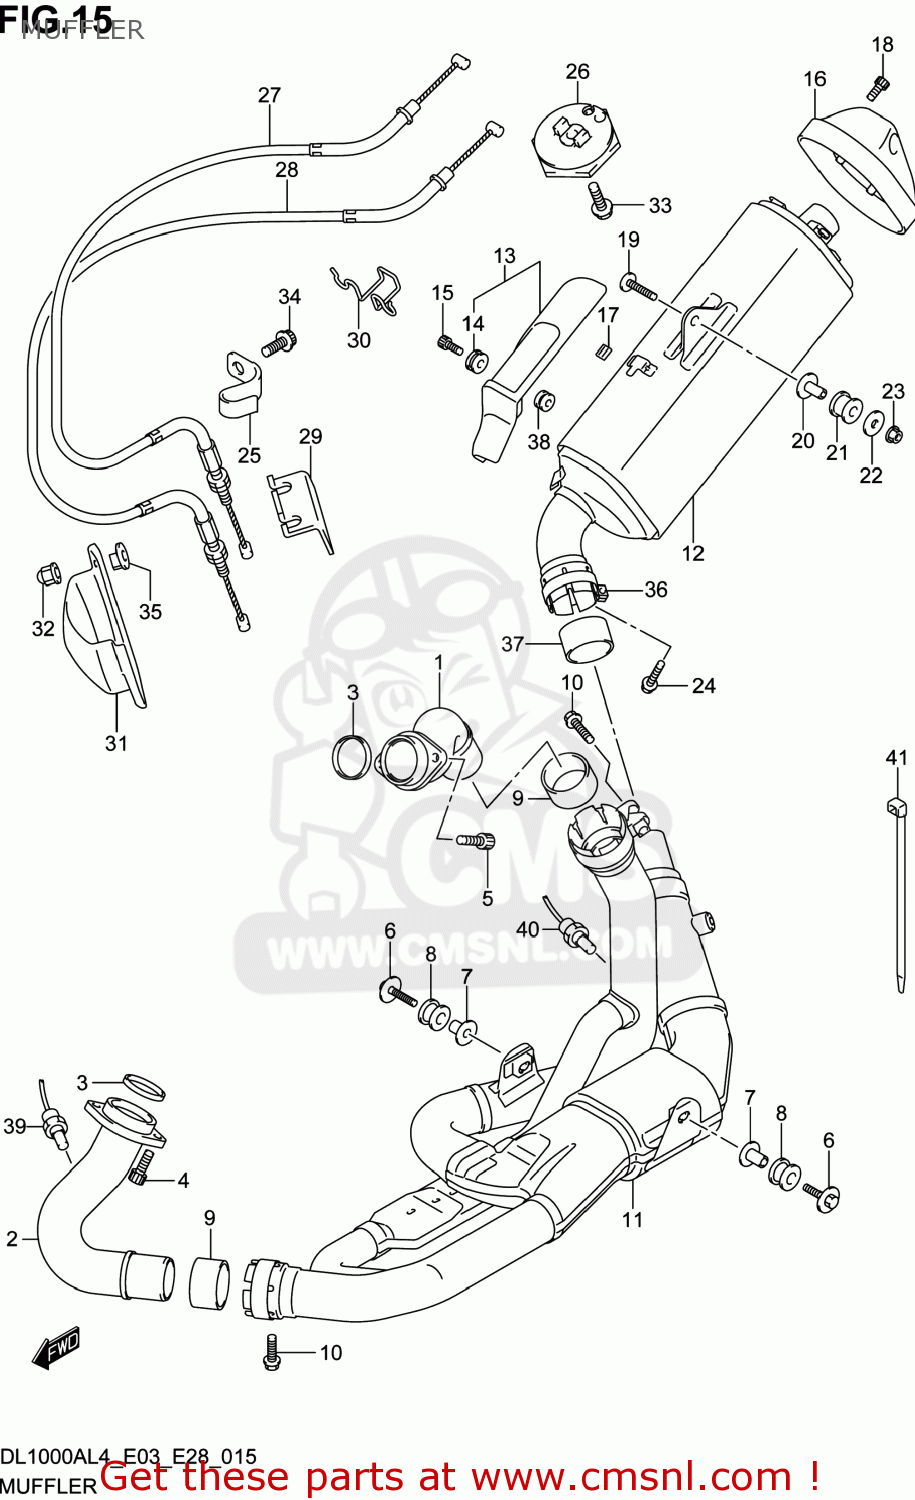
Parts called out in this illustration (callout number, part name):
1	PIPE,EXH RR
2	PIPE,EXH FR
3	GASKET,EXHAUST PIPE (NAS)
4	BOLT(8X25)
5	BOLT
6	BOLT(8X45)
7	SPACER(8.6X12X24.2)
8	CUSHION
9	CONNECTOR,JT
10	BOLT(8X35)
11	PIPE,EXH CTR
12	BODY,MUFFLER
13	COVER,MUF FR
14	CUSHION
15	SCREW(6X12)
16	COVER,MUF RR
17	GROMMET
18	BOLT(6X22)
19	BOLT(8X45)
20	SPACER(8.6X12X27.1)
21	CUSHION
22	WASHER(8.5X33X1.5)
23	NUT
24	BOLT(8X35)
25	CLAMP
26	PULLEY,CONTROLLER
27	CABLE,EXH VALVE NO.1
28	CABLE,EXH VALVE NO.2
29	BRACKET,EXHAUST VALVE CABLE
30	GUIDE,EXHAUST VALVE CABLE
31	COVER,EXHAUST VALVE
32	NUT
33	BOLT
34	BOLT
35	NUT
36	CLAMP,MUF CONN
37	CONNECTOR,MUFFLER
38	BUSH
39	SENSOR,OXYGEN
40	SENSOR,OXYGEN
41	CLAMP(L:145)
